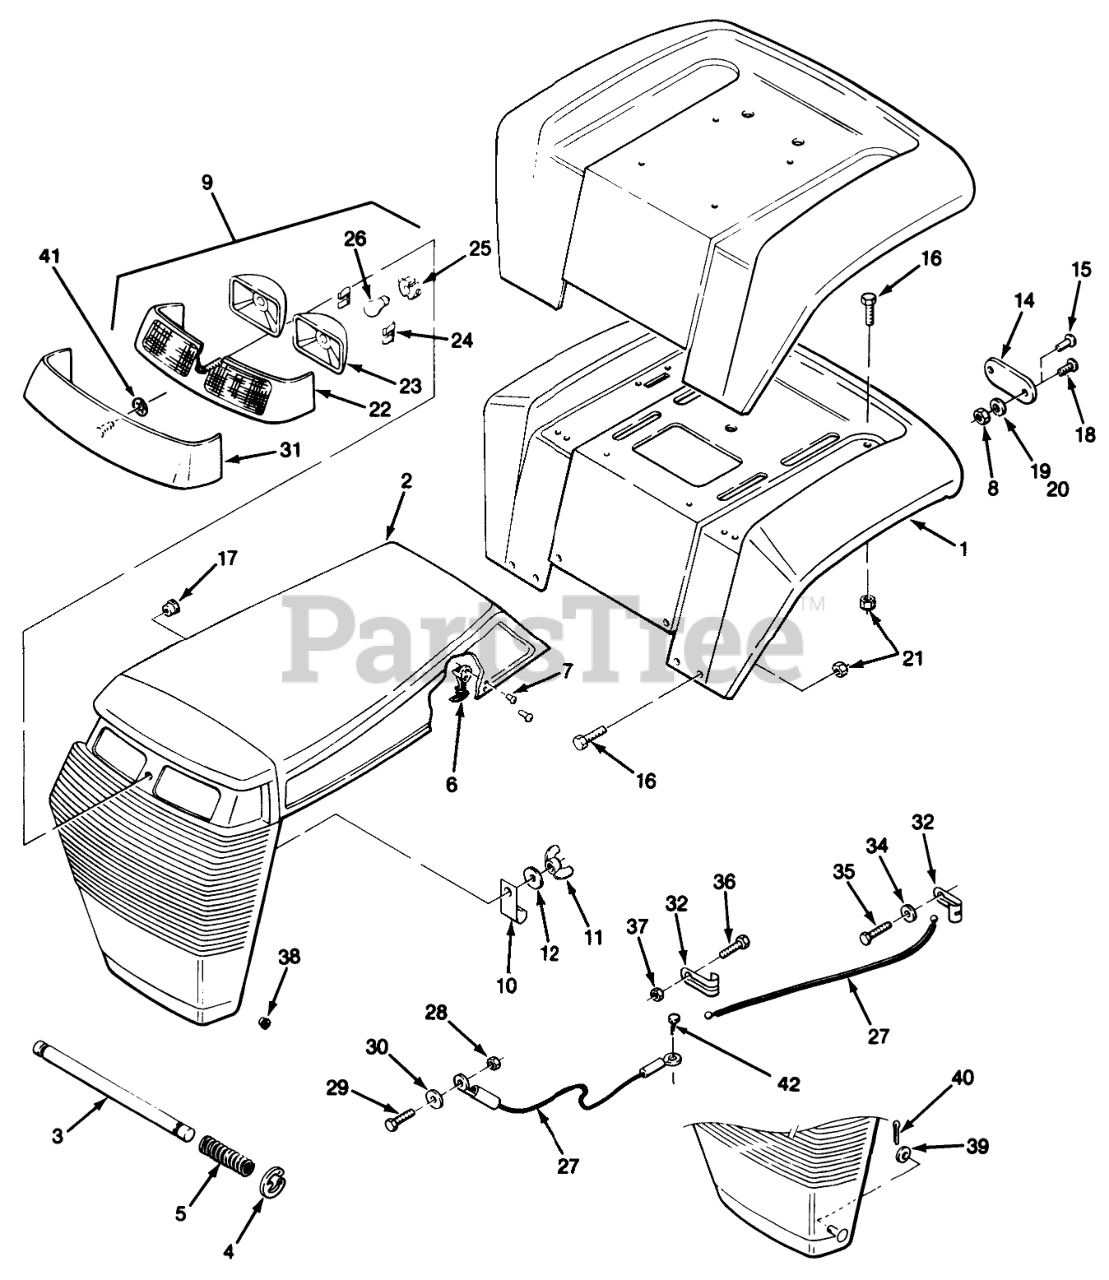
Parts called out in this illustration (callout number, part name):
1	FENDER R
2	Hood & Grill (210-5 & 210-H)
4	E-Ring
5	SPRING
6	HANDLE ASM
7	RIVET-POP
8	Nut
9	Headlight Bar Assembly (Incl. Ref. #22-24 & 26)(212-5 & 212-H)
10	J-CLIP
11	WING NUT
12	WASHER
14	Reflector
15	Poprivet
16	SCREW-CARR
17	BUSHING-NYLON 1.093
18	Screw
19	WASHER
20	Lockwasher
21	Nut
22	LIGHT-BAR BLACK
23	LIGHT POD
24	RETAINER
25	SOCKET-HEADLIGHT
26	BULB
27	CABLE-HOOD LANYARD
28	Nut
29	Screw-Machine
30	WASHER-BACKING
31	COVER-LIGHT OPENING
32	CLEVIS
34	Washer
35	Screw
36	Screw-Machine
37	Nut
38	NYLINER BUSHING
39	WASHER-PLAIN
40	PIN-COTTER
41	RING-RETAINING
42	Screw
